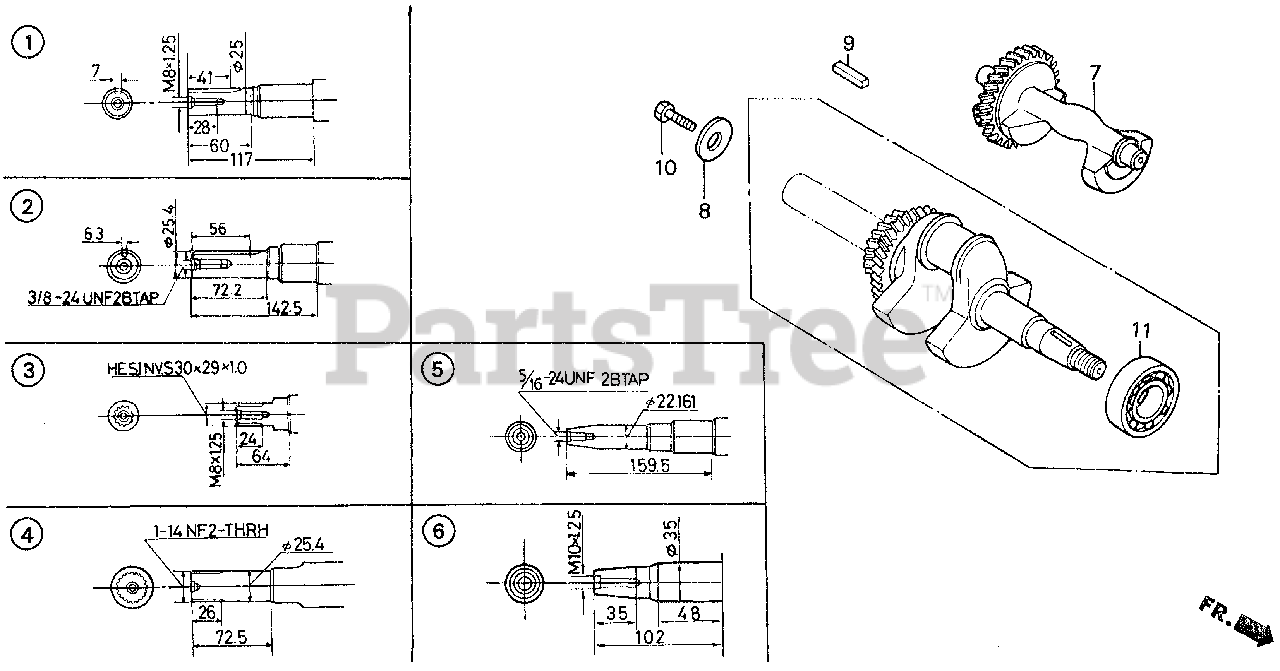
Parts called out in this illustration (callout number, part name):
6	CRANKSHAFT (E-TYPE)
7	WEIGHT, BALANCER
11	BEARING, RADIAL BALL (6207)
